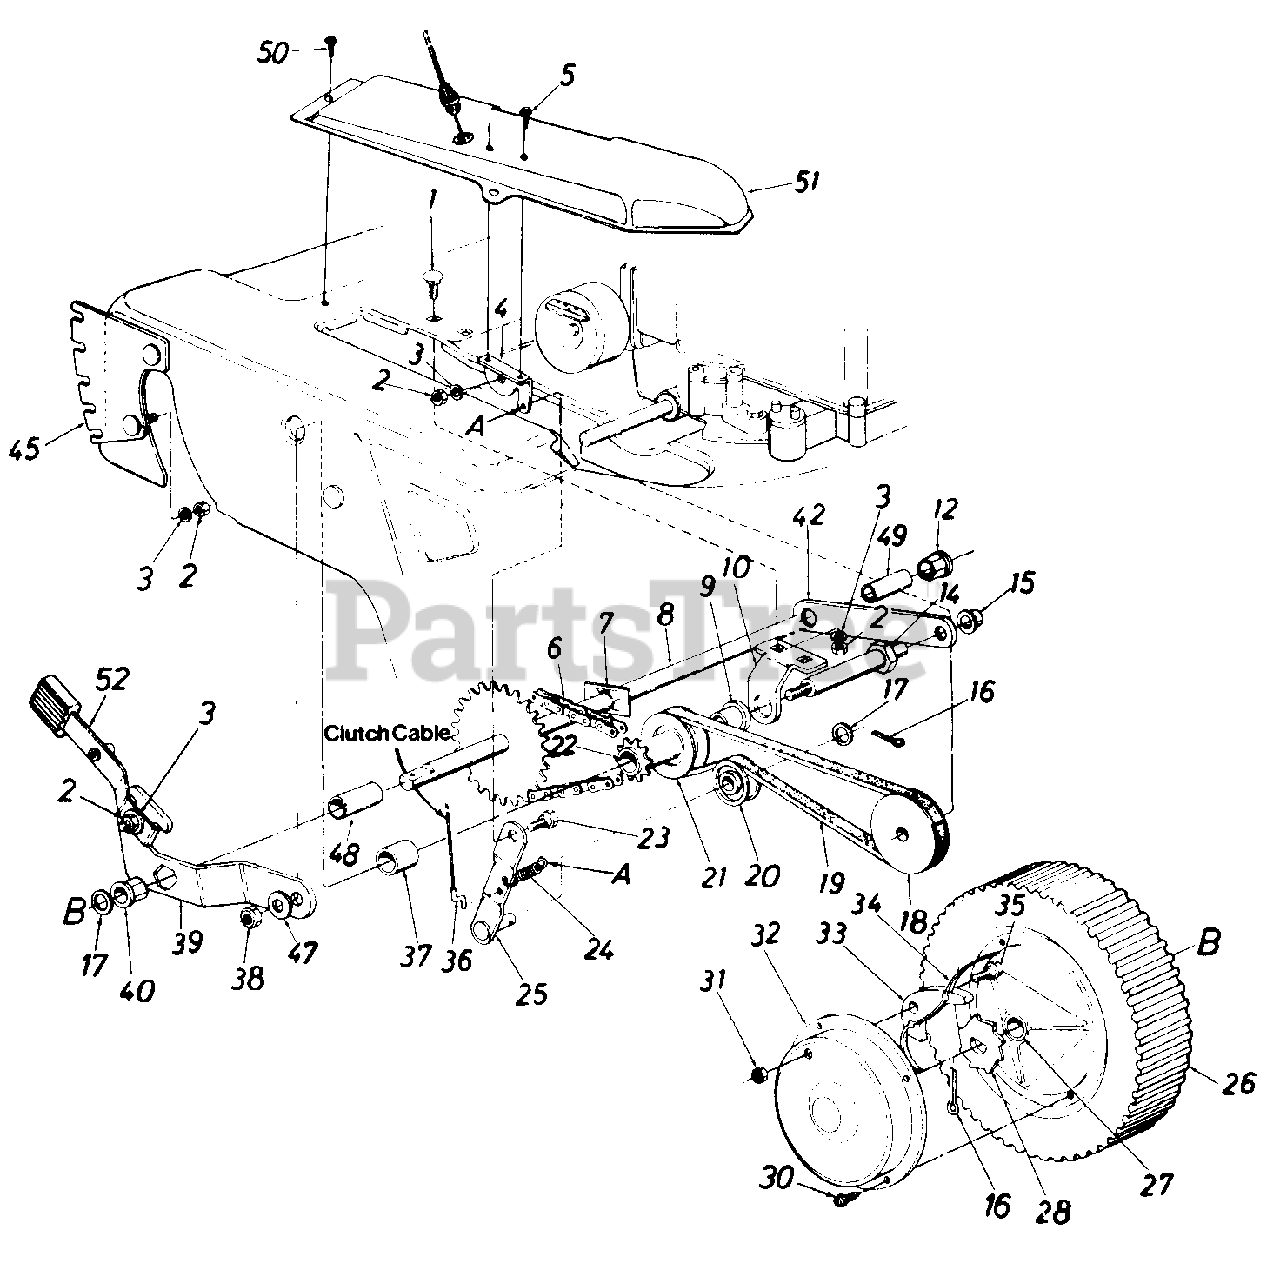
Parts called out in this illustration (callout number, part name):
1	Carriage Bolt 5/16-18 x .62"
2	Hex Nut 5/16-18 Thd.*
3	L-Wash. 5/16" I.D.
4	Cam Bracket
5	Hex "AB" Tap Scr. 1/4 -20 x .62"
6	#48 Chain 1/2" Pitch x 31 Links
7	Push Clip .692 Dia.
8	Rear Shaft Ass'y.
9	Flange Bearing .631" I.D.
10	Bracket
12	Flange Bearing
14	Shld. Bolt .625" Dia. x 3.380
15	Cap Speed Nut .50" Dia.
16	Cotter Pin 1/8" Dia. x 1.0"
17	Fl-Wash. .531 I.D. x .930 O.D.
18	Engine Pulley
19	"V"-Belt
20	Plastic Flat Idler
21	Pulley w/Sprocket Ass'y.
22	Sleeve Bearing .62" I.D.
23	Shld. Bolt .375" Dia. x .171
24	Ext. Spring 1.12" Lg.
25	Idler Bracket Ass'y.
26	Rear Wheel Ass'y. Comp.
27	Flange Bearing .50" I.D.
28	Ratchet-Rear Wheel
30	"AB" Tap Scr. #12 x .50"
31	Hex Ins. L-Nut 1/4-20 Thd.
32	Hub Cap
33	Pawl-Rear Wheel
34	Spring-Nylon
35	Shld. Bolt .342" Dia. x .268"
36	Drive Clutch Cable 59" Lg.
37	Spacer .635 I.D. x .88 O.D.
38	Hex Jam Nut 5/16-18 Thd.
39	Pivot Bracket Ass'y.-R.H.
40	Flange Bearing
42	Support Link
45	Index Plate Ass'y.-R.H.
47	Belleville Washer
48	Spacer
49	Spacer
50	Hex AB-Tap Scr. #10 x .50"
51	Belt Cover
52	Spring Lever Ass'y. w/Knob
